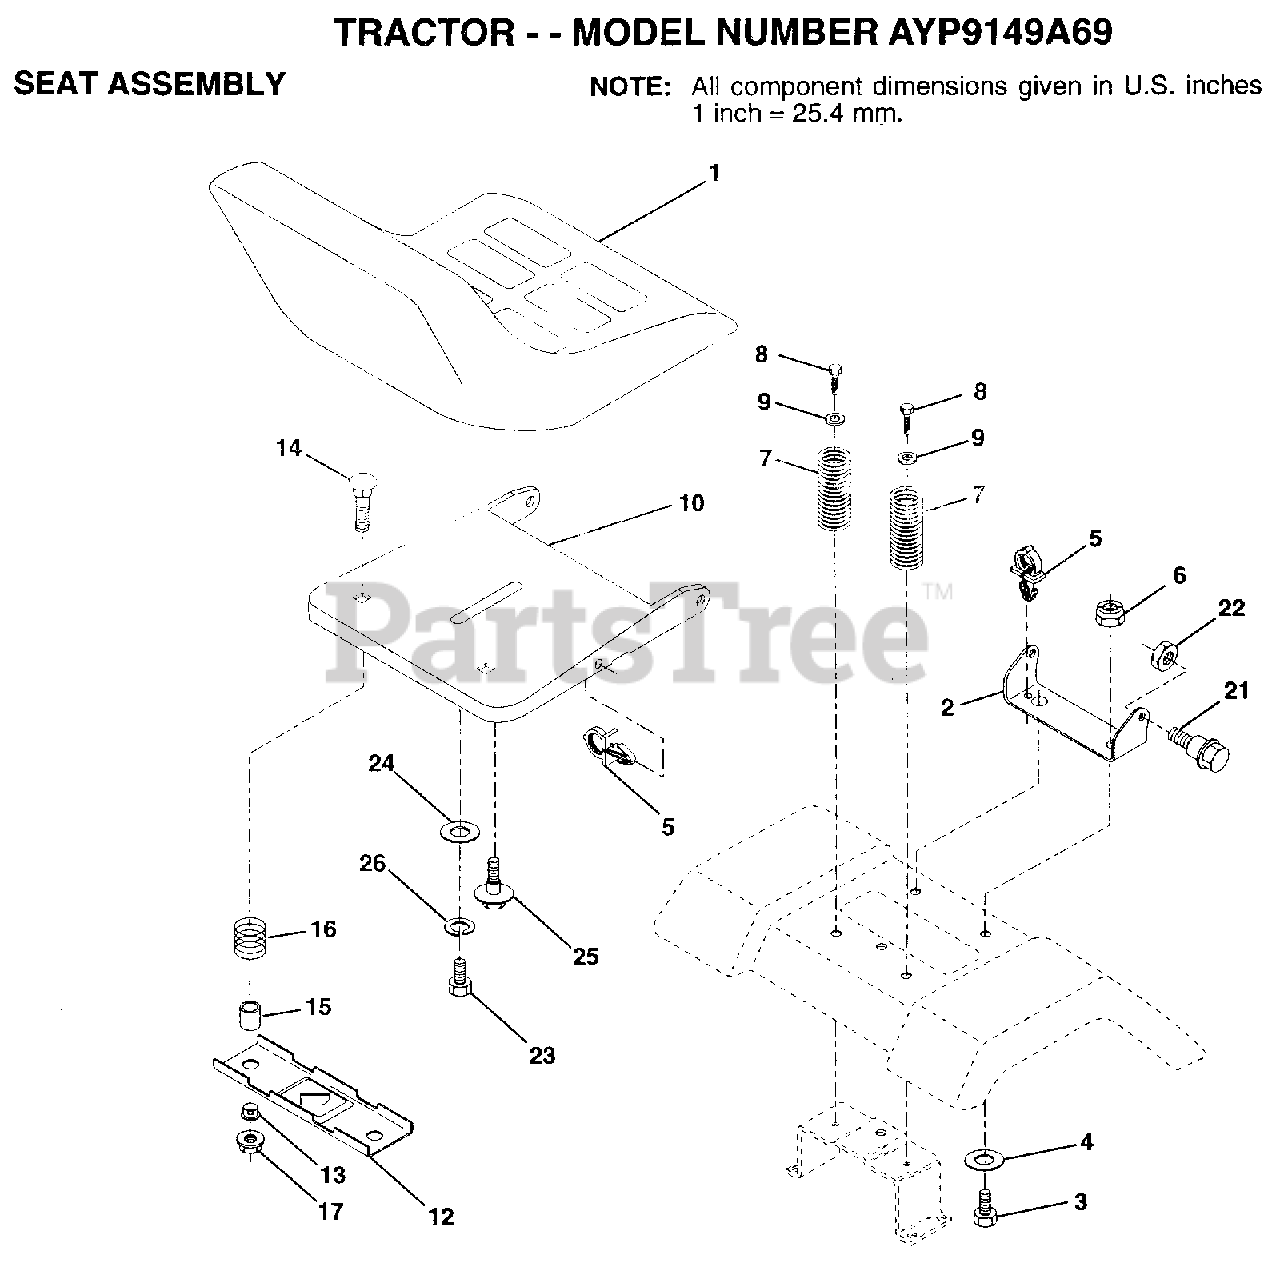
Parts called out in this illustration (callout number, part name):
2	BRACKET PVT SEAT
3	BOLT
4	WASHER PM
5	CLIP.PUSH-IN.HING
6	NUT
7	SPRING COMPRESSIO
8	SCREW GTV
9	WASHER
12	BRKT SWITCH
13	BUSHING
15	SPLIT SPACER
16	SPRING
21	BOLT.SHLD.5/16-18
22	NUT
23	BOLT
24	WASHER
25	"BOLT,SHOULDER"
26	LOCKWASHER
